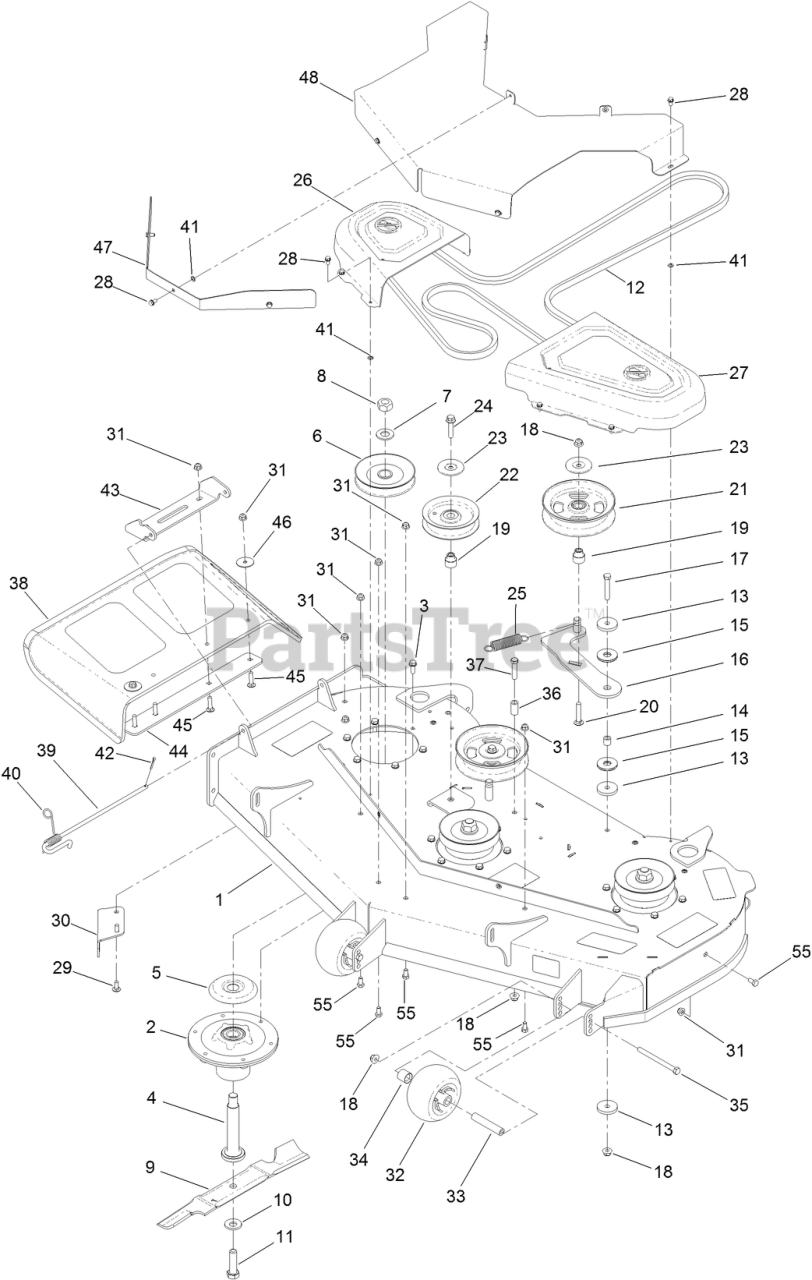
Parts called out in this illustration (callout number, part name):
1	DECK ASM-48"
2	SPINDLE ASM
3	SCREW-TAPTITE
4	SHAFT-SPINDLE
5	SHIELD-BEARING
6	PULLEY
7	WASHER
8	NUT-HEX
9	BLADE - HI FLOW, 16.50 IN
10	WASHER-BELLEVILLE
11	SCREW-BLADE
12	BELT, DECK
13	WASHER-PLAIN
14	BUSHING-IDLER
15	WASHER-FRICTION, COMPOSITE
16	IDLER ARM ASM
17	SCREW-HH
18	NUT-HF, NI
19	BUSHING-IDLER
20	SCREW-CARR
21	PULLEY-IDLER, FLAT
22	PULLEY-IDLER, FLAT
23	SHIELD-DUST
24	SCREW-HHF
25	SPRING-EXTENSION
26	COVER-BELT, RH
27	COVER-BELT, LH
28	SCREW-HWH
29	SCREW-CARR
30	BAFFLE-CUTOFF
31	NUT-HF, NI
32	ROLLER-SCALP, ANTI
33	TUBE-SPANNER
34	SPACER-AXLE, REAR
35	SCREW-HH
36	SPACER-FENDER
37	SCREW-HH
38	DEFLECTOR
39	PIN-CHUTE
40	SPRING-TORSION
41	NUT-RETAINING
42	PIN-COTTER
43	BRACKET UPPER, DEFLECTOR
44	PLATE-DEFLECTOR
45	SCREW-CARR
46	WASHER-FLAT
47	PLATE-GUARD
48	PLATE-GUARD, CENTER
55	SCREW-HH
